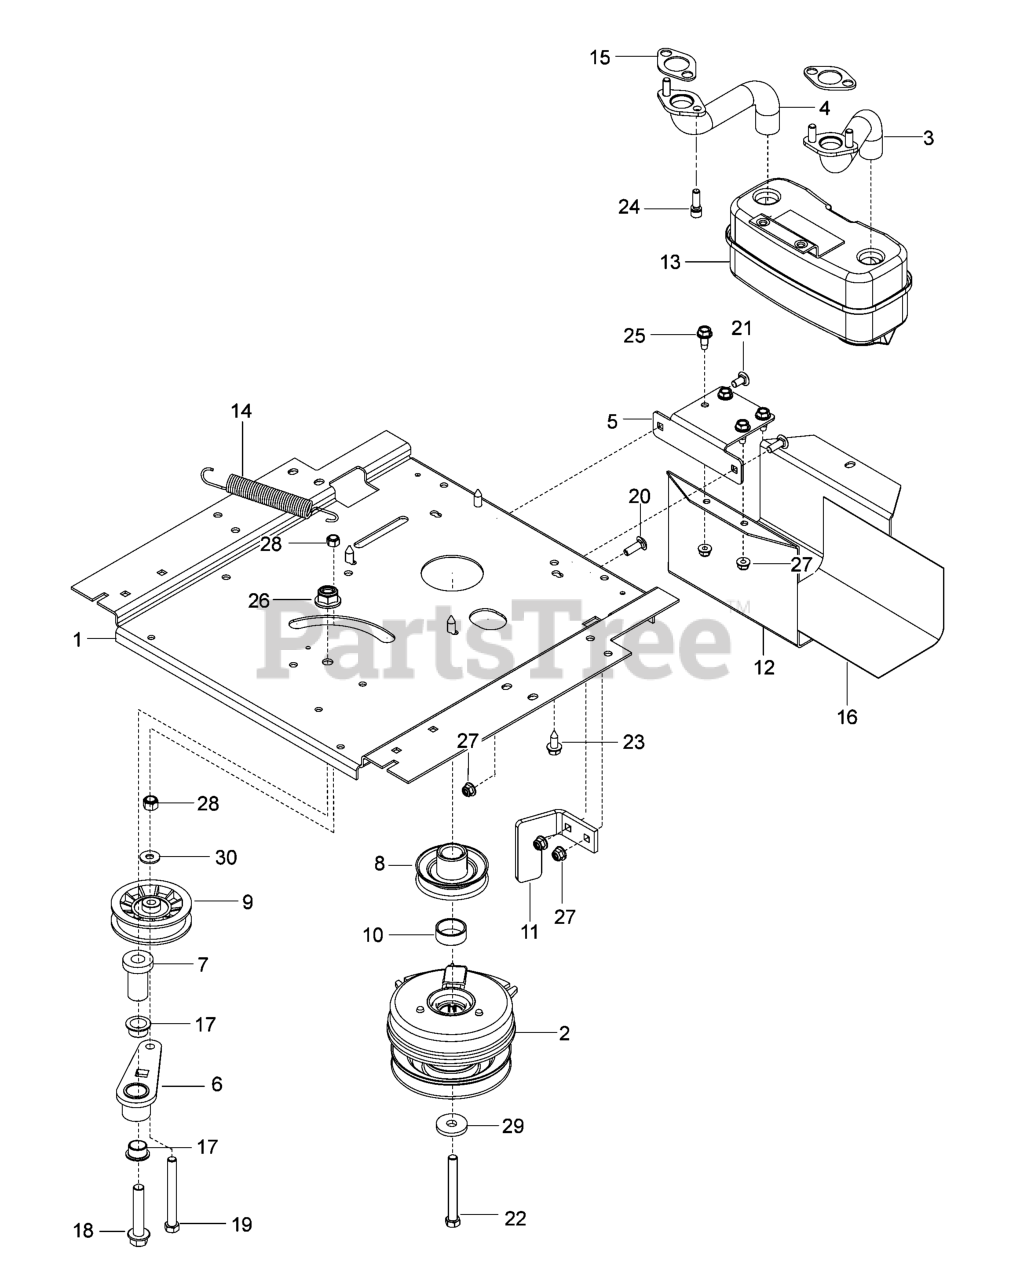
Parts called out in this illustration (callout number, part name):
1	PLATE, Engine
2	CLUTCH ASSEMBLY
3	PIPE-EXHAUST
4	PIPE-EXHAUST
5	BRACKET, Muffler
6	ARM, Idler
8	PULLEY, Crankshaft
9	PULLEY, Idler
10	SPACER, Clutch
11	BRACKET, Clutch
12	GUARD, Muffler
13	MUFFLER ASSEMBLY
16	SHIELD, Muffler
17	BEARING, Flange
18	CAPSCREW, 1/2-13 X 2-3/4 HEX FLANGE HD
19	CAPSCREW, 3/8-16 X 3-1/2 HEX HD
20	CAPSCREW, 5/16-18 X 1 GR. 5
21	BOLT, 5/16-18 X 3/4 GR. 5 ZD
22	CAPSCREW, 7/16-20 X 2-1/2 HEX HD
23	SCREW, 3/8-16 X 1
24	Screw Socket HD 5/16-18 x 1
25	SCREW, 5/16-18 x 3/4 Thred Roll
26	LOCKNUT, 1/2-13 HEX FLANGE NYLOC
27	LOCKNUT, 5/16-18 HEX FLANGE NYLOC
28	LOCKNUT, 3/8-16 HEX NYLOC
29	Washer 1-1/2 OD x 15/32 ID x .250
30	Washer 13/32 x 7/8 x 14 Ga.
